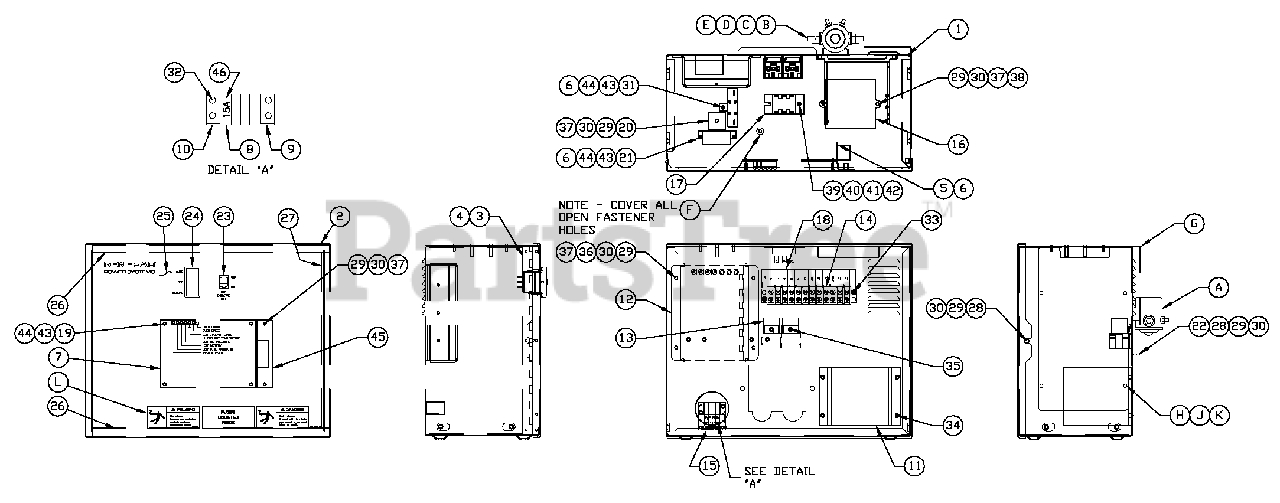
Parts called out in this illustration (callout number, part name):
1	ENCL HSB CONTROL PANEL
2	COVER CONTROL PANEL
3	HINGE CONTINUOUS H-PANEL
4	RIVET POP .125 X .275 SS
5	SCREW PHM M3-0.5X 10MM
6	WASHER FLAT M3
7	ASSY PCB CPL2 CTRLR 3600 RPM
8	HOLDER, FUSEWICKMANN 178.6150
9	ADPTR.RH SIDEWICKMAN 178.6191
10	ADPTR,LH SIDEWICKMAN 178.6192
11	ASSY PCB 2AMP 12V UL BATT CHGR
12	ASSY VOLTAGE REGULATOR 60HZ
13	RELAY, 12VDC C FORM W/DIODE
14	BLOCK TERM 20A 12 X 6 X 1100V
15	DECAL CPL CONTROL PANEL FUSES
16	ASSY PCB BOSCH GOV DRIVER
17	ASSY PCB SCR BRIDGE
18	DECAL CPL 3.9LTB1
19	SPACER 9.5H 3.2 ID
20	DIO BRIDGE 25A 600V
21	CIRCT BRK7X 1 ETA 46-500-P
22	PLATE,HARNESS CLAMP
23	SWITCH RKR DPST 125V SPD
24	SWITCH RKR DPDT ON-OFF-ON
25	DECAL, CONTROL HSB
26	SEAL COVER 3.18X12.7X382
27	SEAL COVER 3.18X12.7X283
28	SCREW HHPM M5-0.8 X 12
29	WASHER FLAT M5
30	WASHER LOCK M5
31	RES WW 15R 5% 25 W QK CONN
32	SCREW PHTT M3.5-0.6 X 10
33	SCREW PHTT M3.5-0.6 X 16
34	SCREW PHTT M4-0.7 X 12 ZYC
35	SCREW PHTT M4-0.7 X 10 ZYC
36	SCREW PPHM M5-0.8 X 12 ZNC
37	NUT HEX M5-0.8 G8 CLEAR ZINC
38	SCREW PPHM M5-0.8 X 30 SS
39	SCREW PPHM M4-0.7X 16
40	WASHER FLAT M4
41	WASHER LOCK #8-M4
42	NUT HEX M4-0.7 G8 YEL CHR
43	WASHER LOCK M3
44	NUT HEX M3-0.5 G8 YEL CHR
45	SUPPORT ANGLE PCB
46	FUSE ATO TYPE 15 AMP (BLUE)
47	HARN 3600RPM R200 CONTROL PNL
A	RELAY SOLENOID 12VDC PNL MNT
B	SCREW HHC 1/4-20 X 3/4 G5
C	WASHER FLAT 1/4-M6 ZINC
D	WASHER LOCK M6-1/4
E	NUT HEX 1/4-20 STEEL
F	SEAL WEATHER .45"DIA
G	COVER CONTROL PANEL SIDE
H	SCREW PPHM M5-0.8 X 12 ZNC
J	WASHER LOCK M5
K	WASHER FLAT M5
L	DANGER HIGH VOLTAGE (SPANISH)
